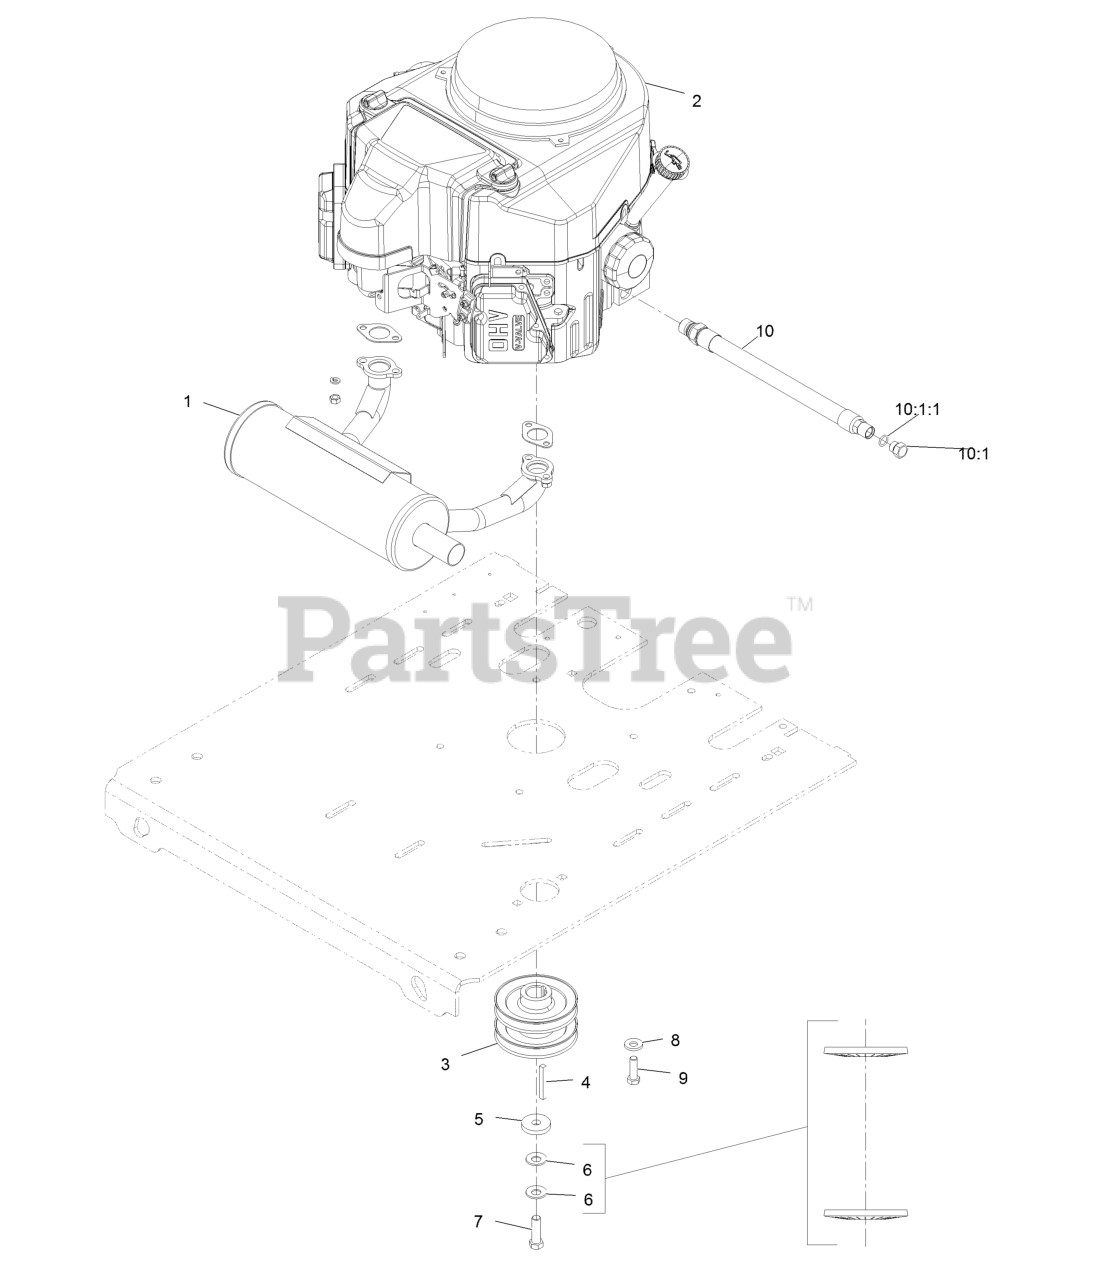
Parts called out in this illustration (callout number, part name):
1	Muffler-Horizontal
6	Washer-Spring Disc 7/16
7	Screw-HH 7/16-20 X 1 1/2 W/Loctite
8	Washer-Spring Disc 3/8
9	Screw-HH 3/8-16 X 1 1/4
10	Asm-Hose Oil Drain W/Plug
10:1	Plug-W/O-Ring
10:1:1	O-Ring
